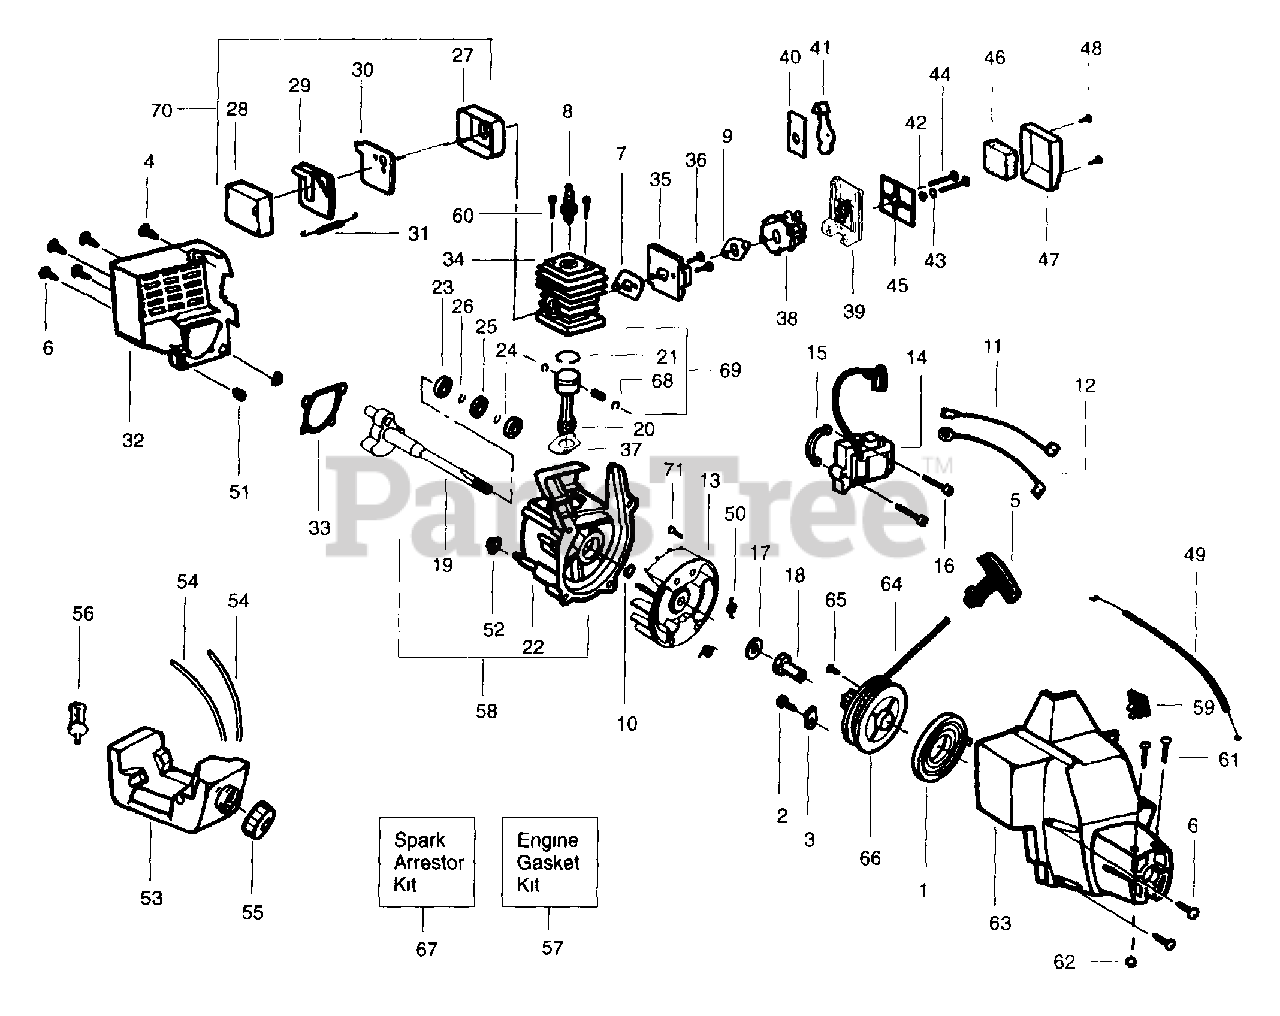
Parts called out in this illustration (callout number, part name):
1	Starter Spring
2	Screw - Pulley
3	Retainer
4	Screw - Fan Hsg/Shroud
5	Starter Handle
6	Screw - Shroud
7	Cylinder/Carb. Gasket
8	Spark Plug (RCJ-8Y)
9	Gasket - Carburetor
10	Retainer Ring - C'case
11	Lead Wire Ass'y.
12	Ground Wire Ass'y
13	Flywheel Ass'y
14	Ignition Module
15	Spacer - Ignit Module
16	Screw - Ignit Module
17	Washer - Flat
18	Drive Coupling
19	Crankshaft Ass'y.
20	Connecting Rod Ass'y
21	Piston Ring
22	Crankcase Ass'y
23	Inner Bearing
24	Outer Bearing
25	C'case Seal
26	Retainer - Crankshaft
27	Muffler Body
28	Muffler Cover
29	Muffler Baffle - Exit
30	Muffler Baffle - First
31	Muffler Spring
32	Rear Shroud
33	Gasket - C'case
34	Cylinder Kit
35	Carb Adaptor Kit
36	Screw - Carb Adaptor
37	Gasket - Cylinder
38	Carburetor Kit w/Limiter Cap
40	Choke Plate
41	Choke Shutter
43	Choke Spacer
44	Screw - Carburetor
45	Filter Plate
46	Air Filter Foam
47	Air Filter Cover
48	Screw - Air Box
49	Throttle Cable Ass'y
50	Spring - Starter Dog
51	Isolator - Shroud
52	Isolator - Crankcase
53	Fuel Tank Ass'y
54	Fuel Line Kit
55	Fuel Cap Ass'y
56	Fuel Pickup Ass'y
57	Engine Gasket Kit
58	C'case & C'shaft Assy
59	On/Off Switch
60	Screw - Cylinder
61	Screw - Pinch Clamp
62	Locknut - Clamp
63	Fan Housing
64	Rope Kit
66	Starter Pulley Kit
67	Spark Arrestor Kit
68	Piston Pin Retainer
69	Piston Kit
70	Muffler Kit
